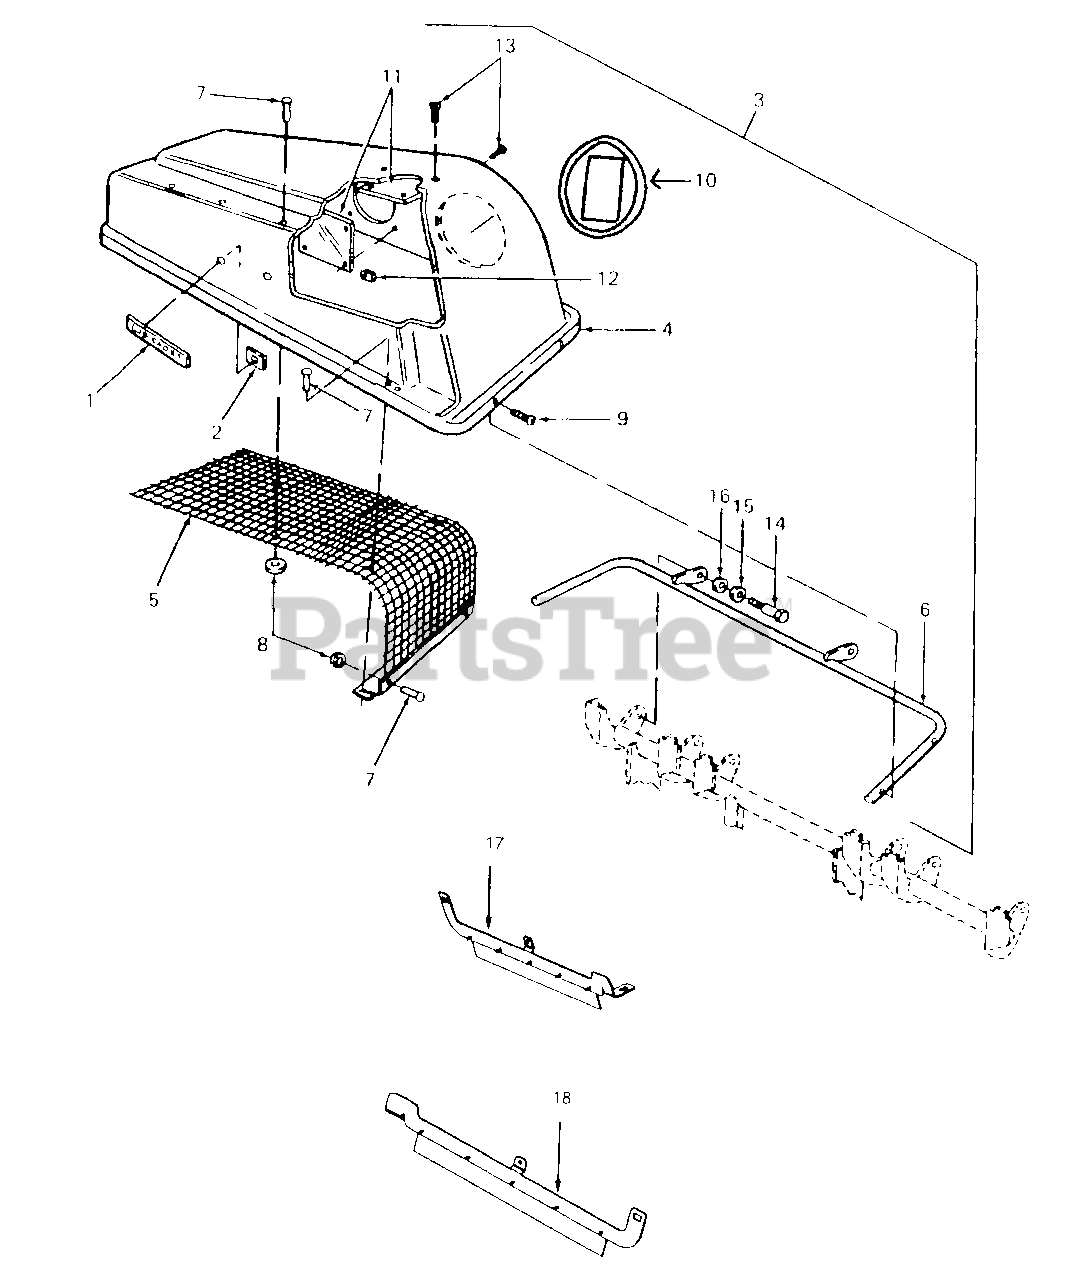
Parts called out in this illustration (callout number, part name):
1	Plaque, Logo w/Studs
2	Nut, Push-on Speed
3	Cover Assy, Grass Catcher
6	Bracket Assy, Catcher Cover Hinge
7	Rivet, Pop
8	Washer, Flat, .218 X .62 X .063
9	Screw, Hex Washer. 1/4 X .50 Lg.
10	Seal, Tube
11	Plate, Plastic, 1/8 Thk X 5.62 Sq.
12	Nut, U-Type Speed
13	Screw, Truss Mach., #10 X .50 Lg.
14	Screw, Shld.
15	Washer, Flat, .510 X.75 X .033
16	Washer, Bell, .515 X 1.14
